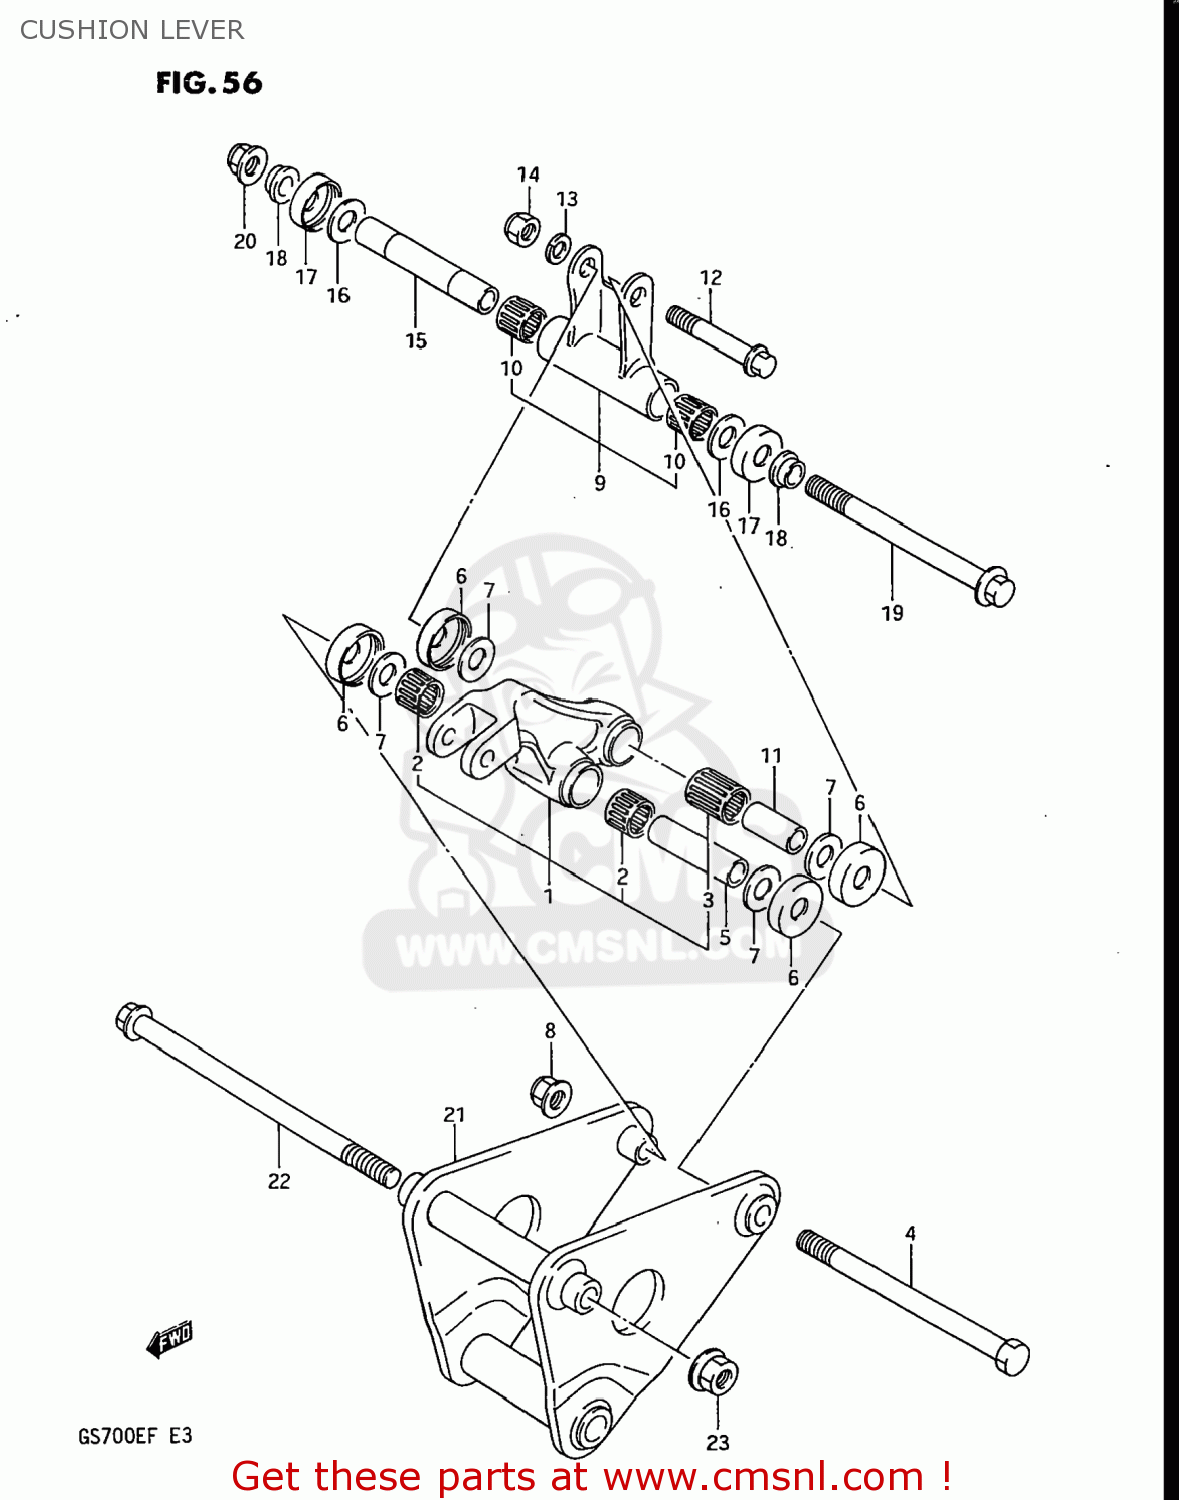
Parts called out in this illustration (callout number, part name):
1	LEVER SET,REAR CUSHION
2	ROLLER BEARING (17X24X2
3	ROLLER BEARING (17X24X25)
4	SHAFT,RR CUSHION LEVER
5	SPACER,REAR CUSHION LEVER
6	COVER,RR SWGARM DUST SEAL
7	WASHER
8	NUT 12MM
9	ROD SET,REAR CUSHION
10	ROLLER BEARING (17X24X2
11	SPACER,RR CUSHION LEVER ROD UP
12	BOLT, UPPER
13	WASHER
14	NUT
15	SPACER,RR CUSHION LVR ROD LOW
16	WASHER
17	COVER,RR SWGARM DUST SEAL
18	SPACER,REAR CUSHION ROD
19	BOLT,CUSHION ROD
20	NUT 12MM
21	BRACKET,REAR SHOCK ABSORBER
22	SHAFT,SHOCK ABSORBER BRACKET
23	NUT
